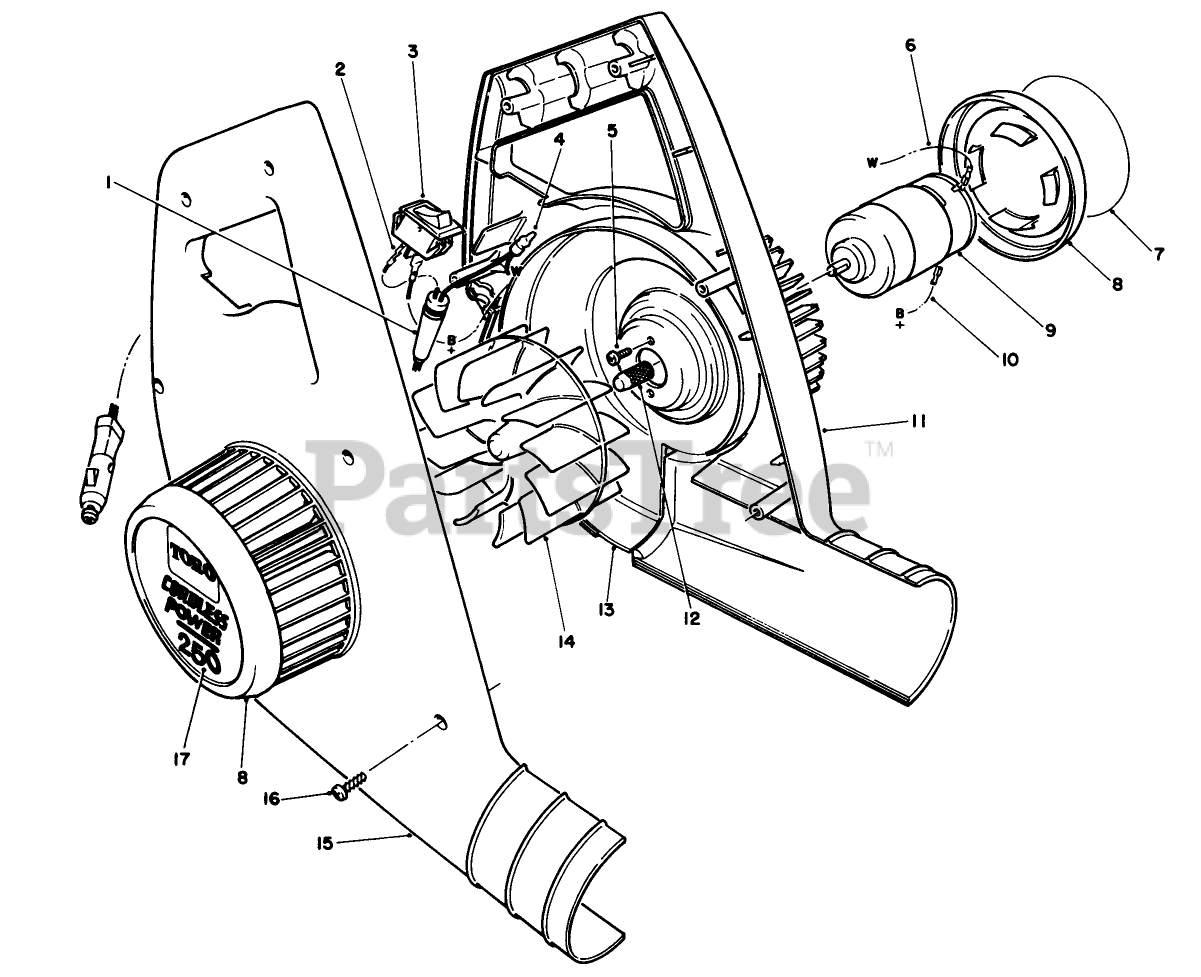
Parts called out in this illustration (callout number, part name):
1	POWER SUPPLY CORD
2	Terminal-Female
3	ROCKER SWITCH W/LETTERS
4	CONNECTOR WIRE JOINT
5	SCREW
6	WIRE ASSEMBLY
7	LABEL-SERIAL (250 CL)
8	MINI BV-INTAKE COVER
9	Motor-12 Volt
10	WIRE ASSEMBLY
11	Housing-L.H.
12	Shaft-Knurled
13	Cover-Motor
14	Impeller
15	HOUSING,RH,MINI-BLOWER
16	Screw
17	COVER LABEL(250 CORDLES
